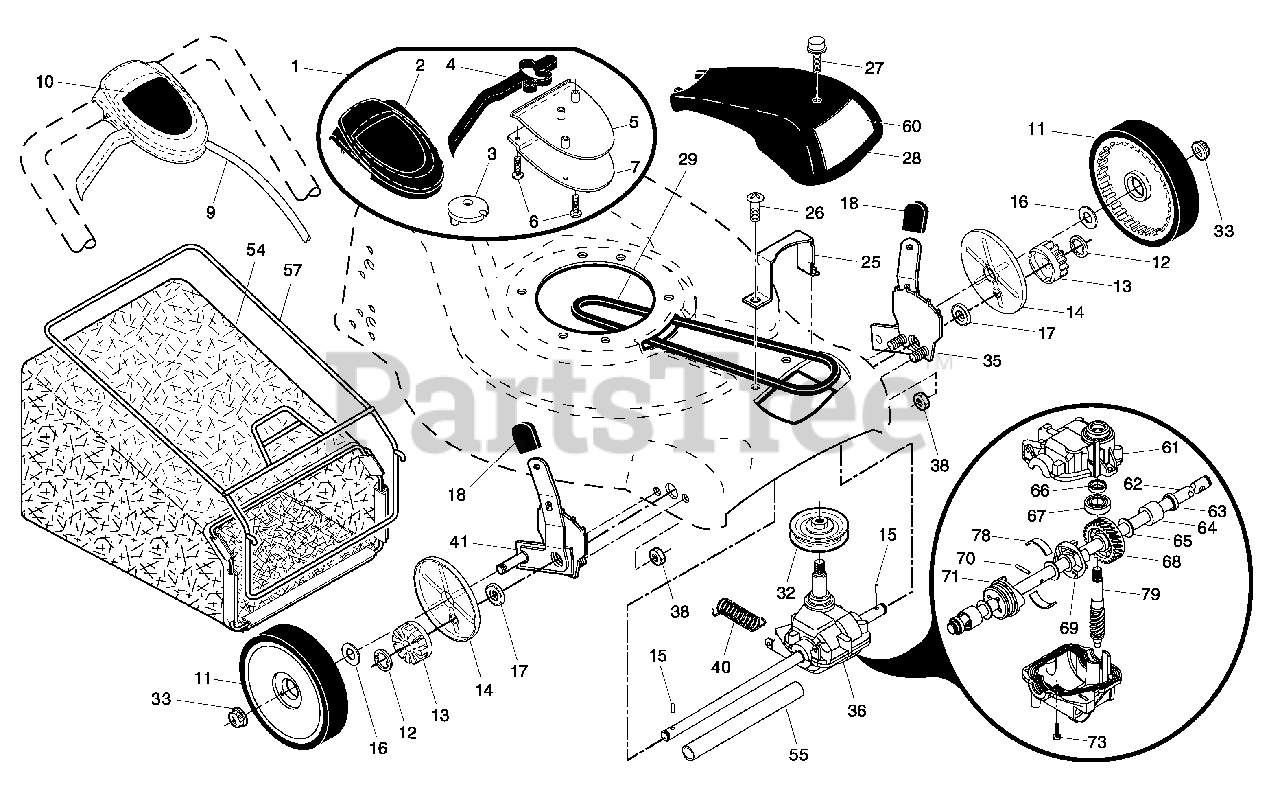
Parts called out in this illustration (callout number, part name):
1	Drive Control Assembly
2	Cover, Drive Control, Upper
3	Pulley
4	Lever, Drive Control
5	Cover, Drive Control, Lower
7	Mounting Bracket, Drive Control
9	Cable, Drive
10	Decal, Drive Control
11	Wheel & Tire Assembly
14	Dust Cover
15	Pawl, Drive
16	Washer 1/2 x 1-1/2 x .134
17	Bearing, Wheel Adjuster
18	Selector Knob
25	Belt Keeper
27	Screw, Pan Head, Self-Tapping #10-24 x 2-3/4
28	Drive Cover
32	Drive Pulley
33	Locknut, Hex
35	Kit, Wheel Adjuster, LH
36	Gearcase Assembly, Complete
38	Locknut, Hex 1/4-20
41	Kit, Wheel Adjuster, RH
54	Grassbag Assembly
55	Driveshaft Cover
57	Frame, Grassbag
60	Decal, Drive Cover
61	Case, Upper
62	Shaft, Output
63	Seal, Output Shaft
66	Seal, Worm Shaft
67	Bearing, Ball
68	Gear, 28 Teeth
69	Fixed Dog Clutch
70	Pin
71	Movable Dog Clutch
73	Screw, Case
74	Case, Lower
78	Spring, Leaf
79	Shaft, Worm
